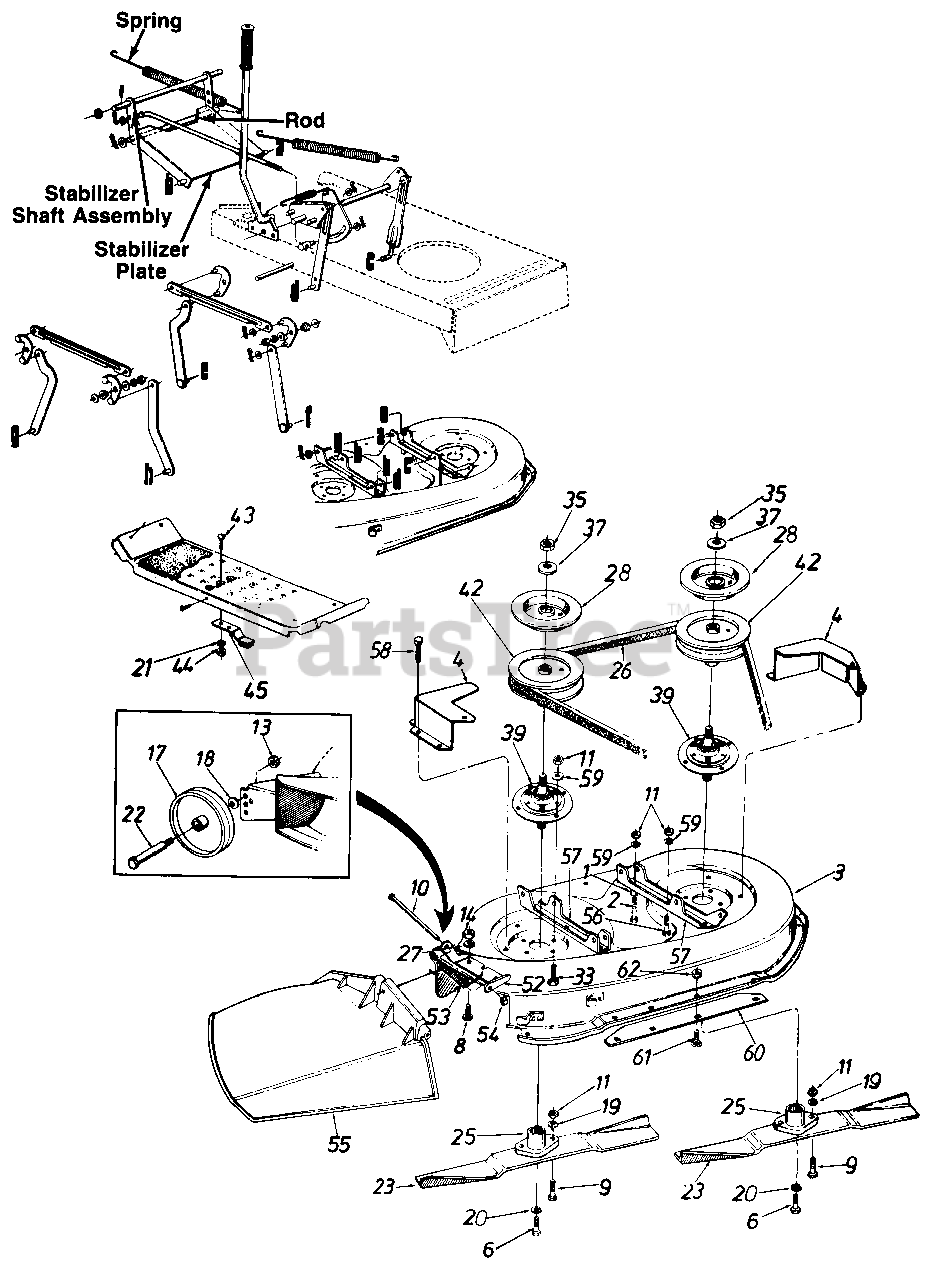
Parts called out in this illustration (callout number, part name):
1	Spacer .33" I.D. x .88"
2	Hex Bolt 5/16-24 x 1.25" Lg.
3	38" Deck Ass'y. w/Deck Wheels
6	Hex Bolt 3/8-24 x 1.0" Lg.
8	Hex Bolt 1/4-20 x .62"
9	Hex Bolt Special 5/16-24 x 1.0"
10	Hinge Pin
11	Hex Nut 5/16-24 Thd.
13	Hex Top L-Nut 3/8-16 Thd.
14	Hex Nut 1/4-20 Thd.*
17	Deck Wheel-5"
18	Bell-Wash. .40" I.D. x .88" O.D.t
19	L-Wash. 5/16" I.D.
20	L-Wash. 3/8" I.D.-H.D.
21	L-Wash. 1/4" I.D.
22	Shld. Bolt .498" Dia. x 1.53"
23	High-Lift Blade
25	Blade Adapter
26	V-Belt
27	Bell-Wash. 1/4" I.D.
28	Brake Disc
33	Hex Bolt 5/16-24 x .75" Lg.
35	Hex Jam Nut 5/8-18 Thd.
37	L-Wash. 5/8" I.D.
39	Blade Spindle Ass'y. Comp.
42	5" Dia. Pulley
43	Carr. Bolt 1/4-20 x .62"
44	Hex Nut 1/4-20 Thd.*
45	Blade Brake Ass'y.
52	Hinge Mtg. Brkt.
53	Torsion Spring
55	Chute Ass'y. Comp.
56	Hex Bolt 5/16-24 x .75" Lg.
59	Bell-Wash. .345" I.D. x .88"
62	Hex Sems Nut 1/4-20 Thd.
17665-0483	Belt Guard, Black - CHARCOAL GRAY (0483)
17665-0498	Belt Guard, Black - OLD CUB YELLOW (0498)
17665-0637	Belt Guard, Black - POWDER BLACK (0637)
17665-0638	Belt Guard, Black - MTD/TROY-BILT RED (0638)
17665-0648	Belt Guard, Black - TECH GRAY (0648)
17665-0650	Belt Guard, Black - RED METALLIC (0650)
17665-0662	Belt Guard, Black - OYSTER GRAY (0662)
17665-0665	Belt Guard, Black - YARDMAN GREEN (0665)
